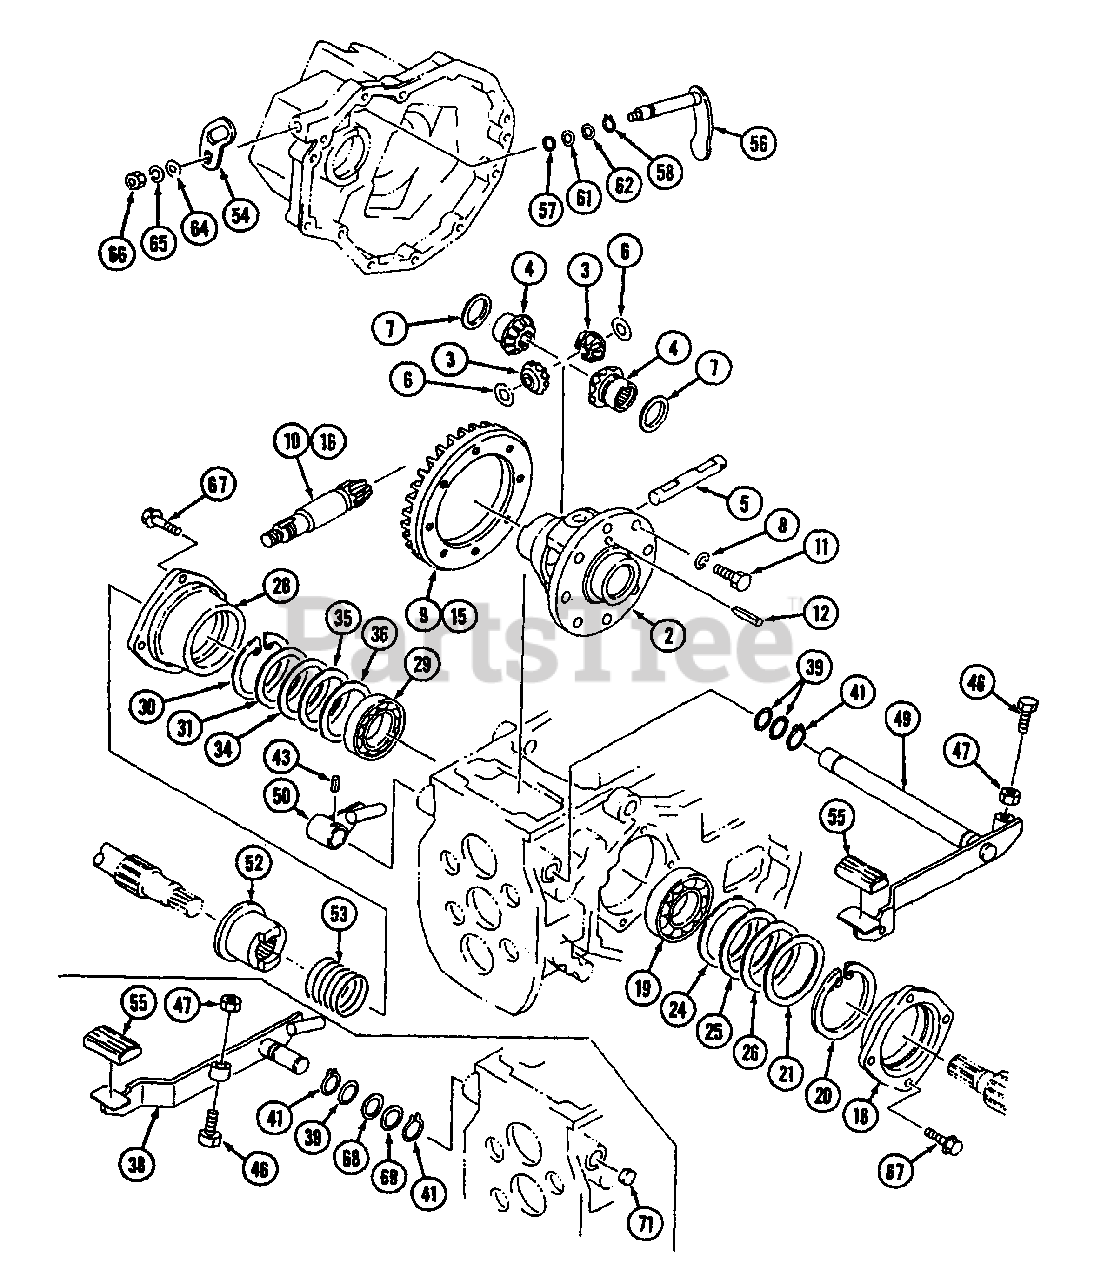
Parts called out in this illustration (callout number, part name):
2	Case, Differential
5	Shaft, Pinion
6	Washer, Thrust
7	Washer, Thrust
11	Bolt, M8-1.25
24	Liner, t=0.07
38	Pedal, Diff. Lock
49	Pedal, Diff. Lock
50	Arm, Diff. Lock
71	Seal, Cap
